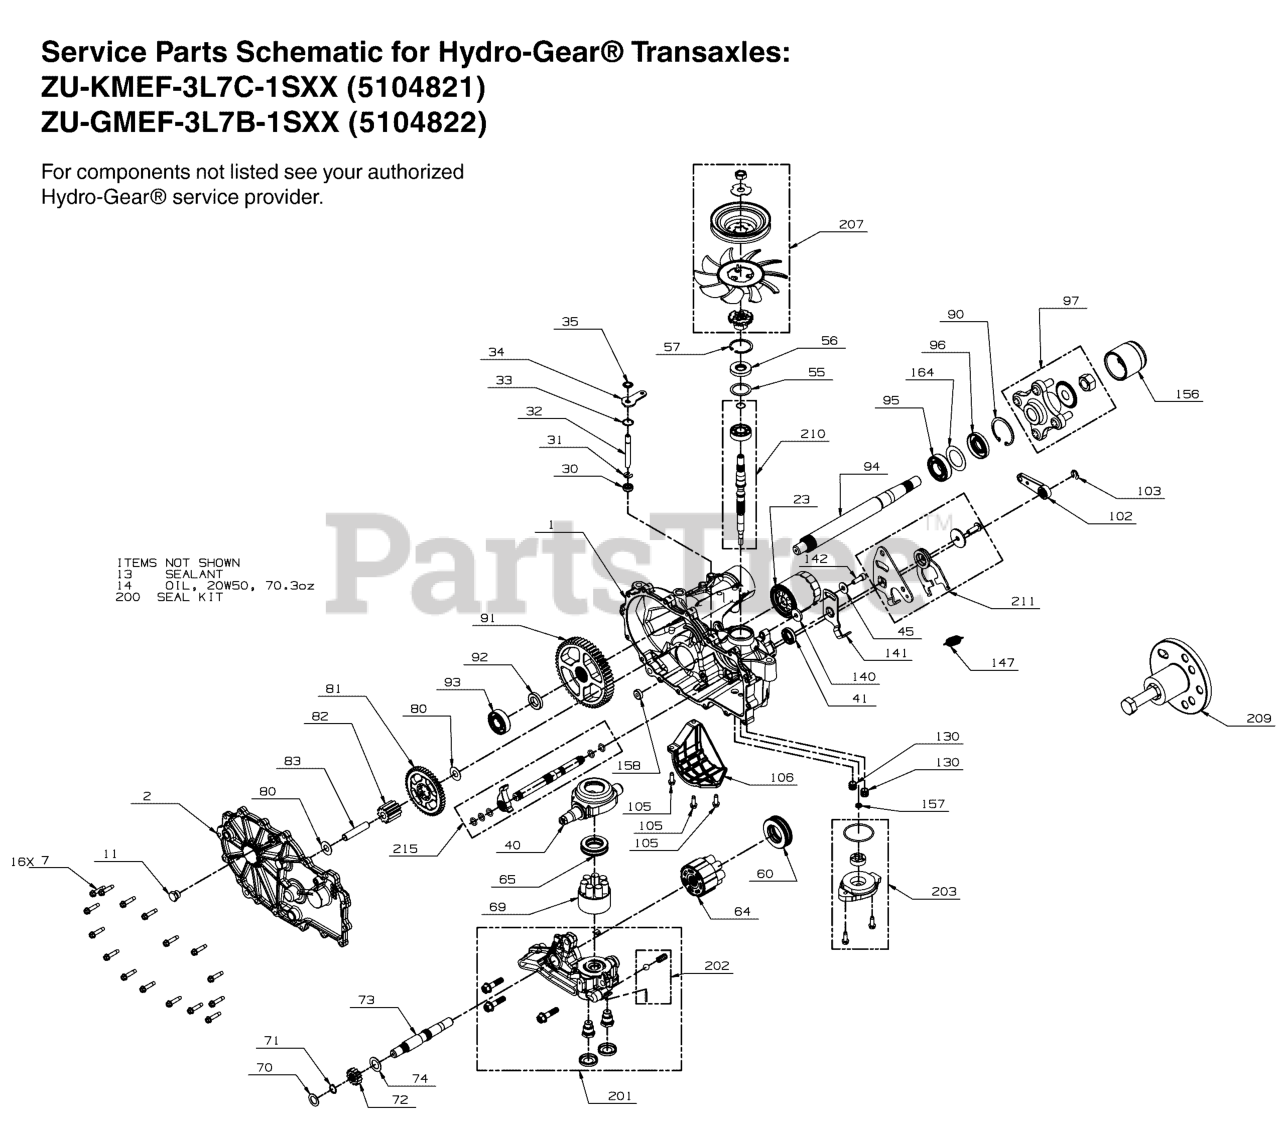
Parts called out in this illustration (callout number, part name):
23	FILTER, OIL, ZT2800
41	SEAL, CONTROL ARM, 18X32X7, #51140
56	SEAL, Lip, .67 x 1.58 x .276
57	RING, RET 2.06 INT,
93	KIT, BEARING, ZT-3400, 72749
94	SHAFT, AXLE, ZT-3400, 53528
95	BEARING BALL, 1.0 X 52 X 15 OPEN 6205M
96	KIT, SEAL, AXLE - HG# 53699
97	HUB, ASM, TRANS 5101188/89 & 5102154/55
102	BRAKE ARM, ZT3400
103	E-CLIP, BRAKE ARM, ZT3100 & ZT3400
156	CAP, AXLE, ZT-3400, 53501
200	KIT, SEAL - HG# 73239
203	KIT, CHARGE PUMP, ZT2800, ZT3100
207	KIT, FAN-PULLEY, ZT-3400, 72684
210	KIT, INPUT SHAFT (BEARING AND SHAFT ONLY)
1000	KIT, PLUG, BRAKE BORE, OUTBOARD
